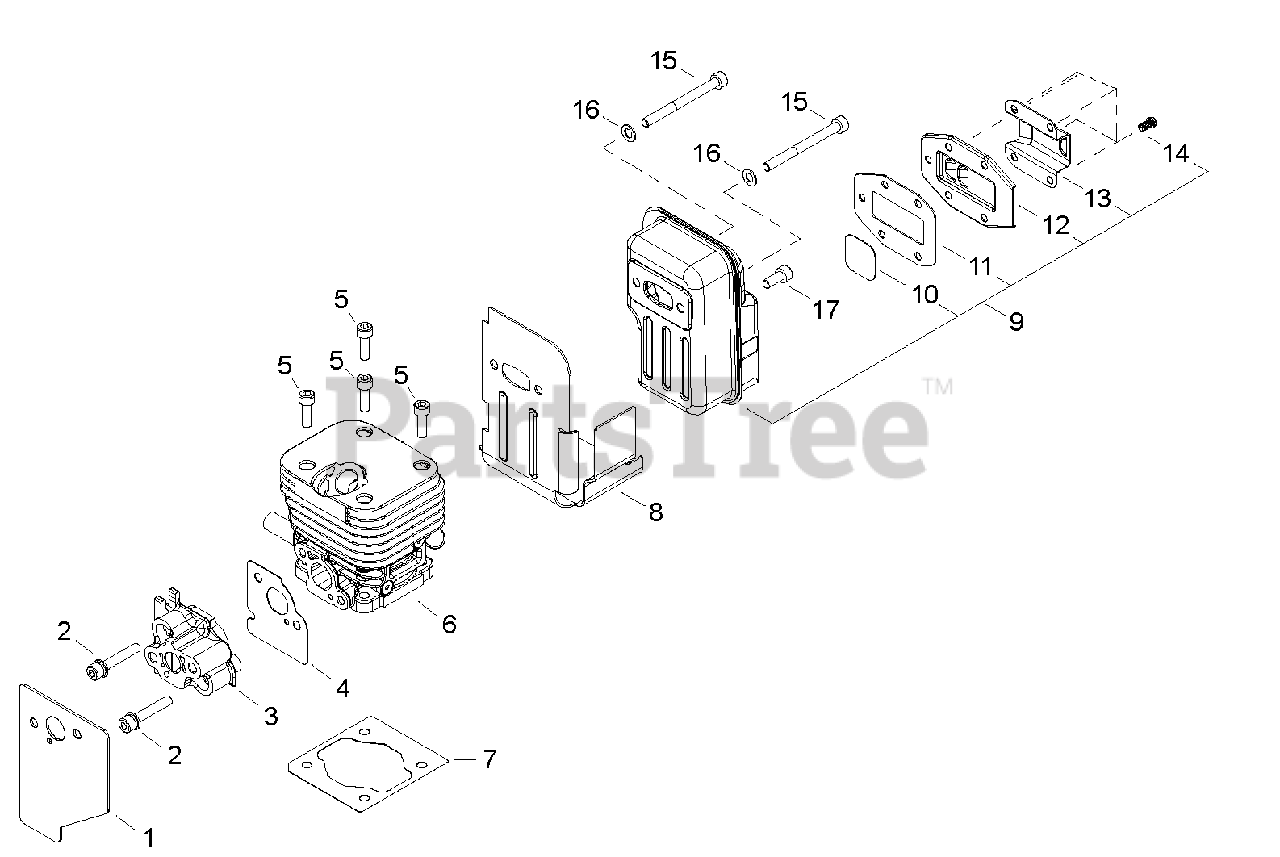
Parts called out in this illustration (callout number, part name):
1	GASKET, INTAKE
2	SCREW - 5X30
3	INSULATOR
4	GASKET, INTAKE
5	SCREW - 5X16
6	CYLINDER
7	GASKET, CYLINDER
8	DEFLECTOR, HEAT
9	MUFFLER ASSY
10	SCREEN, SPARK ARRESTOR
11	GASKET, EXHAUST
12	GUIDE, EXHAUST - INNER
13	GUIDE, EXHAUST - OUTER
14	SCREW - 4X8
15	SCREW - 5X55
16	WASHER - 5
17	SCREW - 5X12
